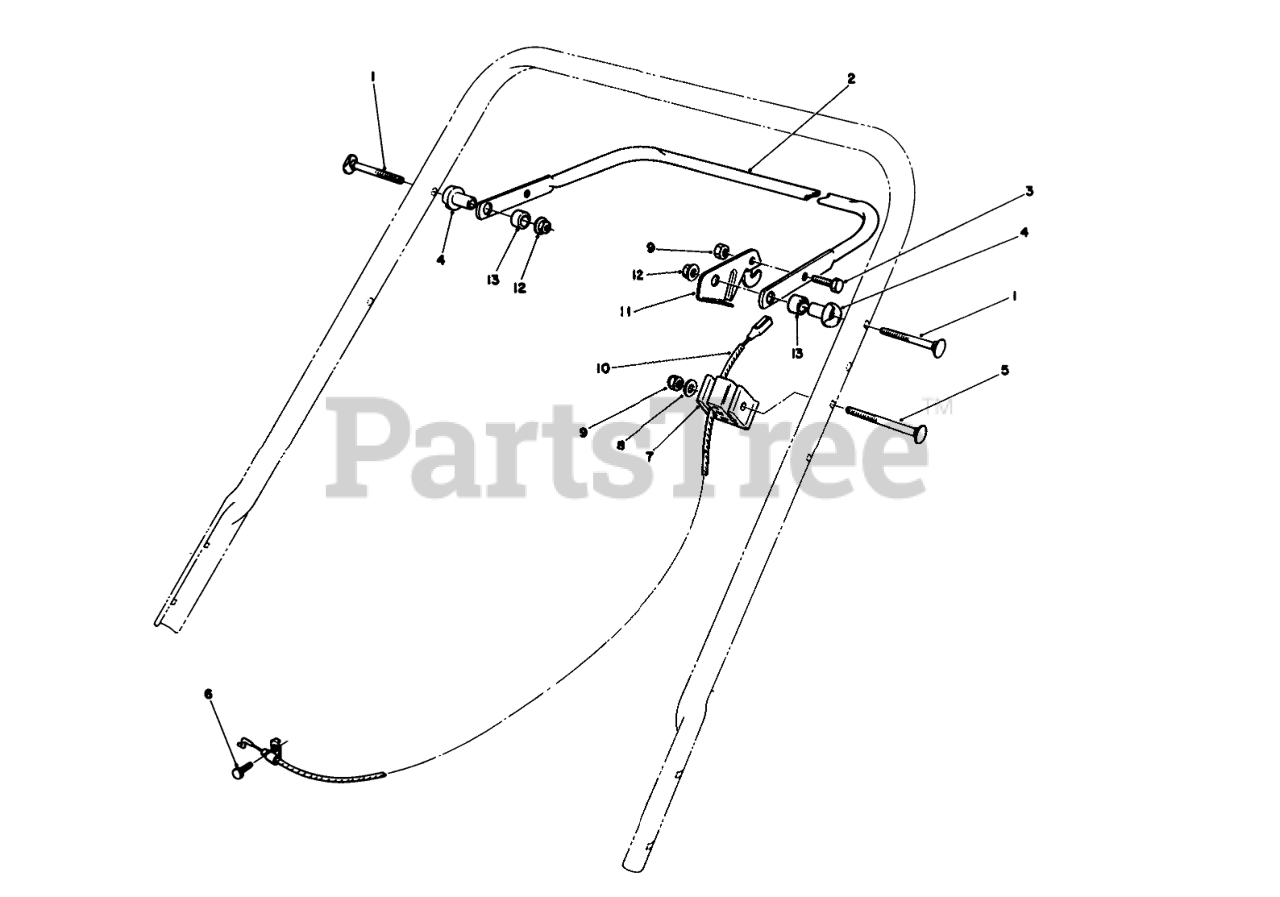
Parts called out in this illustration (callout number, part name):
1	5/16-18 X 2 HNDLE SCREW
2	Bar-Control
3	SCREW-HH
4	SPACER-SUPPORT
5	HANDLE SCREW
6	SCREW-HH
7	SUPPORT-CABLE
8	WASHER-FLAT
9	NUT-LOCK, NI
10	BRAKE CABLE
11	CONTROL LEVER
12	NUT-LOCK, NI
13	SPACER-NYLON
